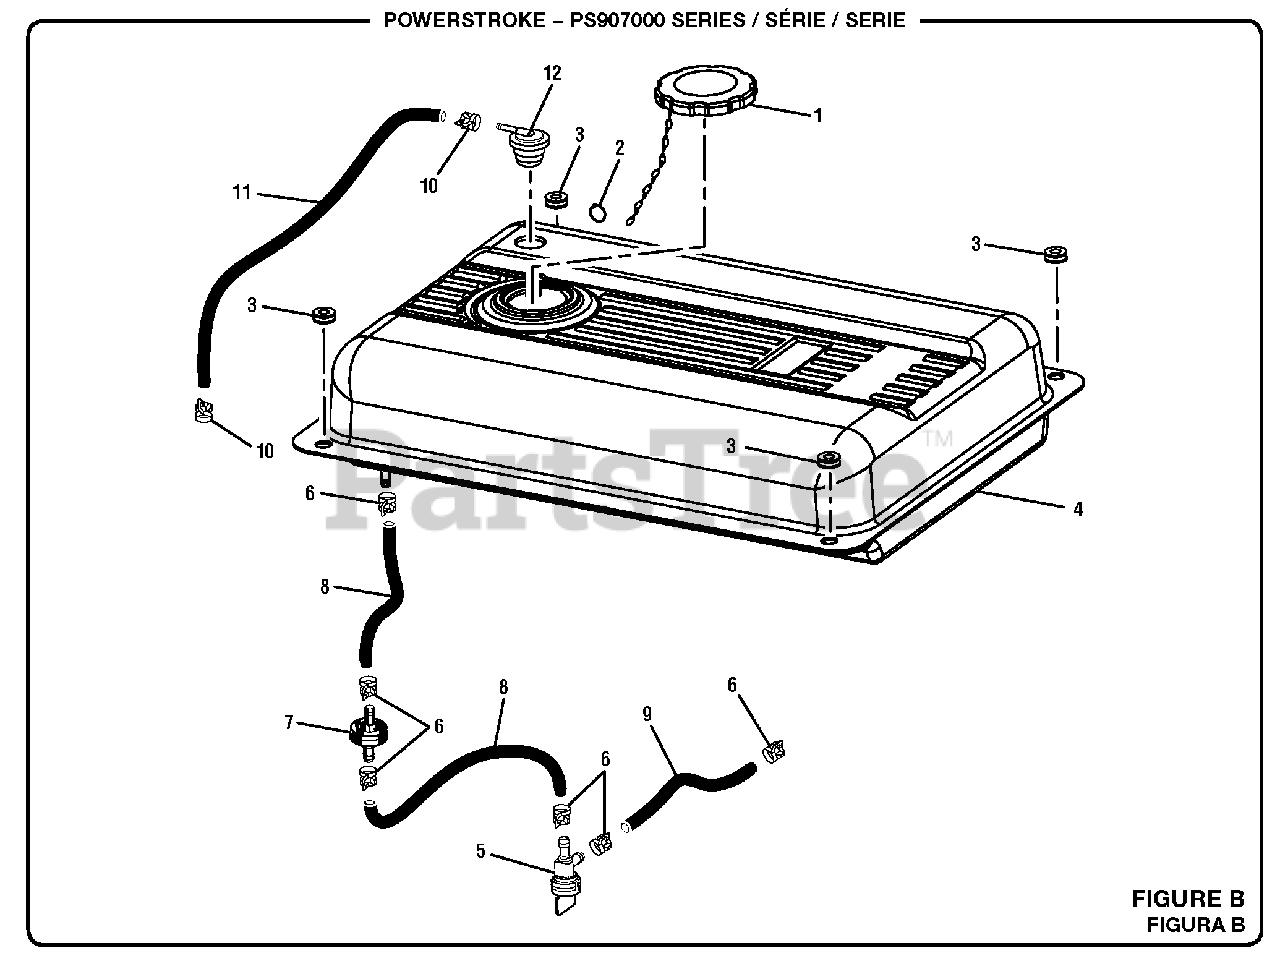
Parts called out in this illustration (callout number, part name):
1	Fuel Tank Cap
2	Ring Clip
3	Bushing w/Insert
4	Fuel Tank
5	Fuel Valve
6	Fuel Line Clamp (1/2 in.)
7	Fuel Line Filter
8	Fuel Line (1/4 in.)
9	Fuel Hose (1/4 in.)
10	Fuel Line Clamp (7/16 in.)
11	Vapor Hose
12	Vapor Vent
